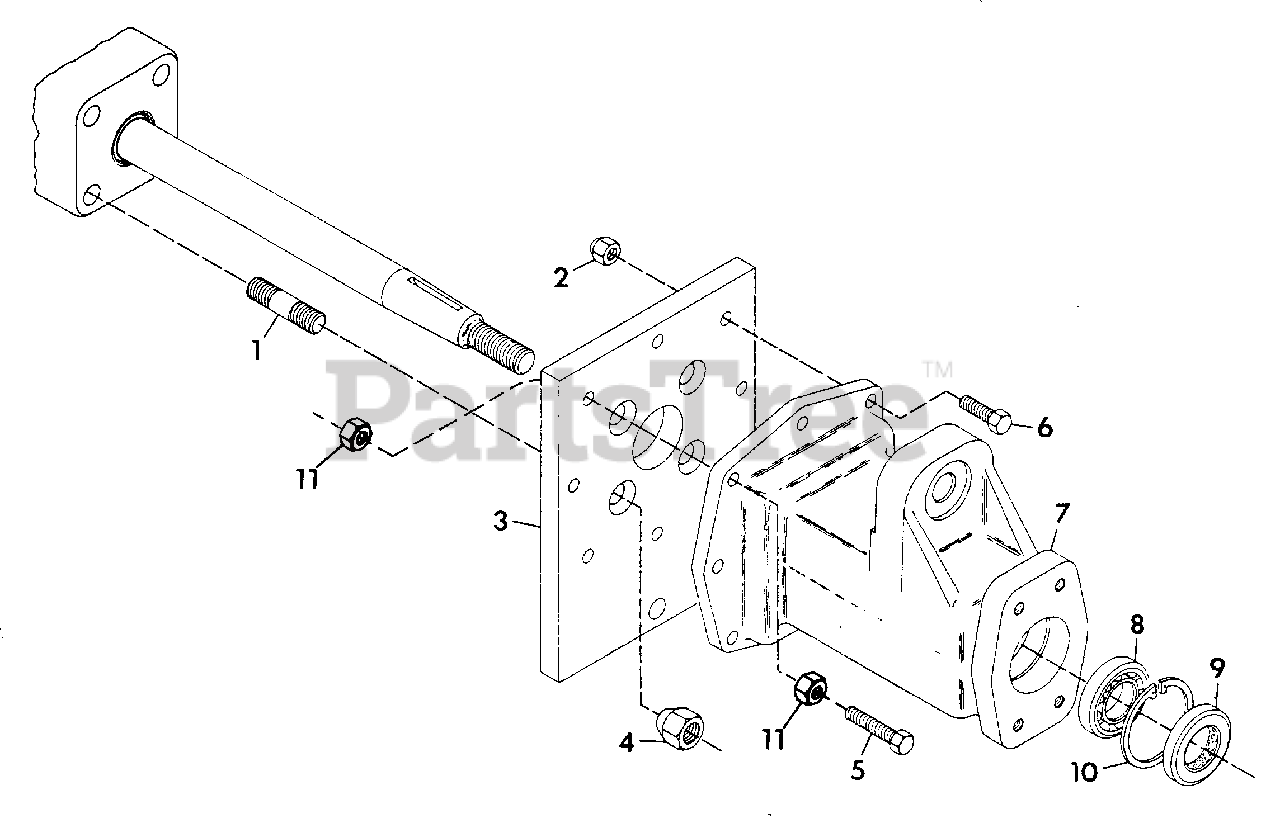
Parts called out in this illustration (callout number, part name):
1	STUD, AXLE
2	NUT, LOCK 3/8-16
3	PLATE, AXLE
4	NUT, RIM
5	BOLT, HEX 3/8 - 16 X 2.00
6	BOLT, HEX 3/8 - 16 X 1.50
7	HOUSING, AXLE OFC
8	BEARING, BALL 1.250 X 2.250 X .500
9	SEAL, OIL AXLE
10	RING, RETAINING
11	NUT, JAM 3/8 - 16 HEX
